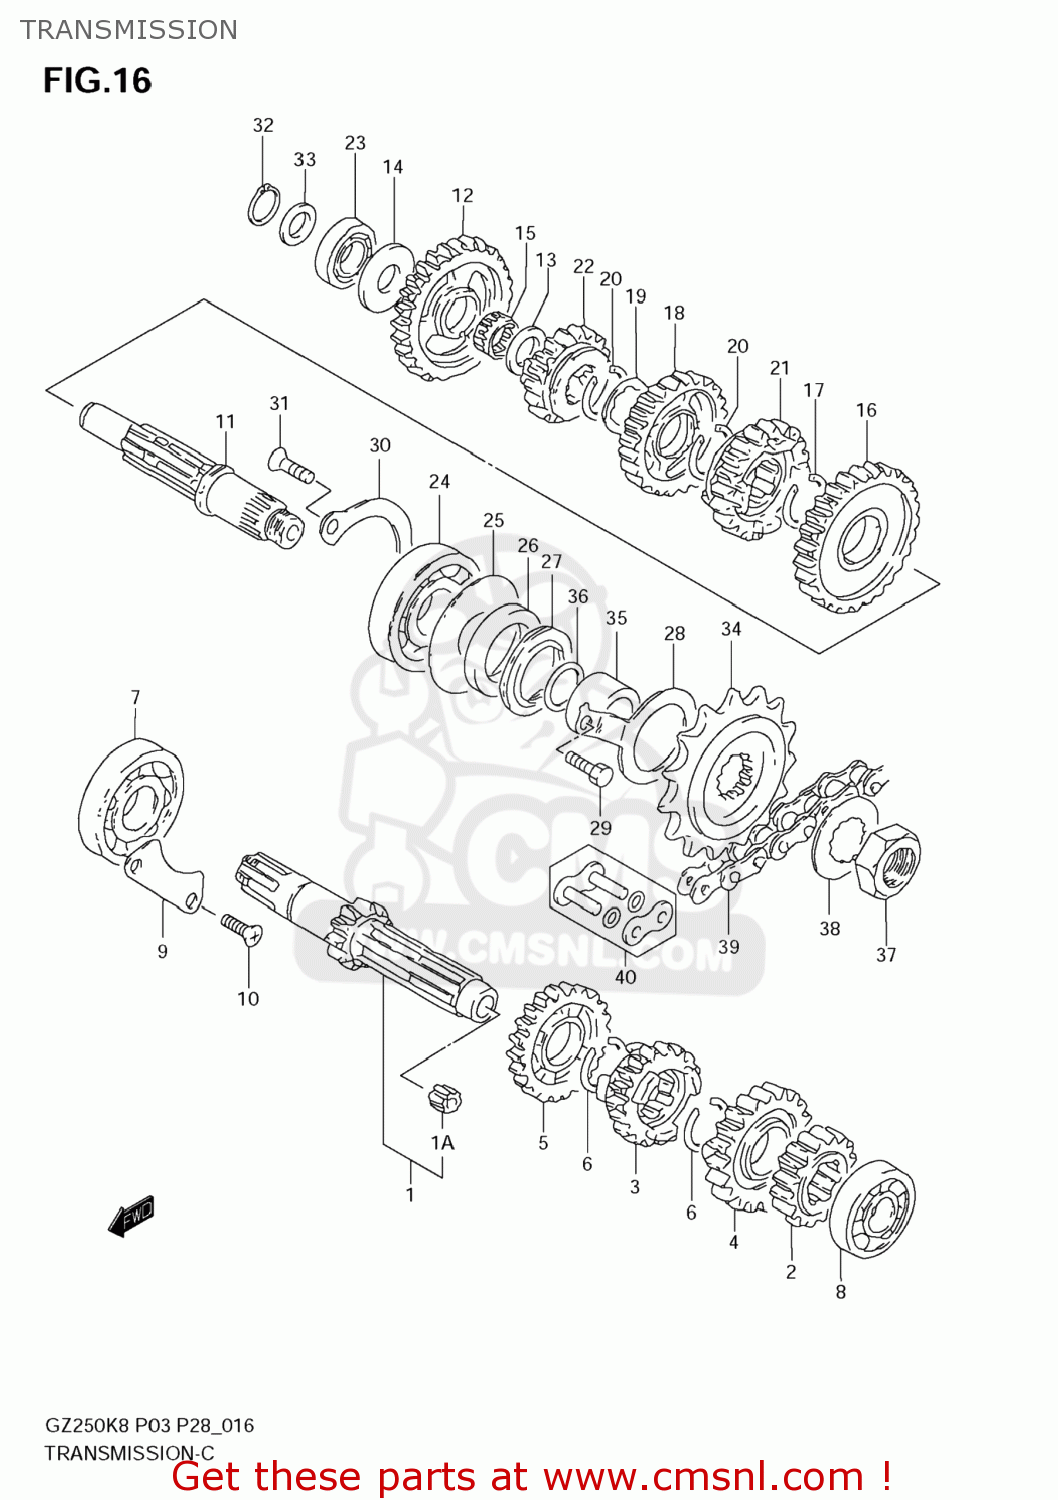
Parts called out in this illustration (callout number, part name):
1	SHAFT,COUNTER(NT:11)
1A	BUSH
2	GEAR,2ND DRIVE(NT:16)
3	GEAR,3RD DRIVE(NT:19)
4	GEAR,4TH DRIVE(NT:20)
5	GEAR,5TH DRIVE(NT:22)
6	CIRCLIP
7	BEARING(22X56X16)
8	BEARING(17X40X12)
9	RETAINER,CNTR SHAFT BEARING
10	BOLT(6X12)
11	SHAFT,DRIVE
12	GEAR,1ST DRIVEN(NT:29)
13	SHIM(17X28X1)
14	WASHER
15	BEARING(17X21X9.8)
16	GEAR,2ND DRIVEN(NT:27)
17	CIRCLIP
18	GEAR,3RD DRIVEN(NT:24)
19	WASHER,LOCK
20	CIRCLIP
21	GEAR,4TH DRIVEN(NT:20)
22	GEAR,5TH DRIVEN(NT:18)
23	BEARING(17X36X12)
24	BEARING(22X56X16)
25	WASHER(35X55X1)
26	SEAL,OIL(30X43X5)
27	SEAL,OIL(30X43X7)
28	RETAINER,DRIVE SHAFT OIL SEAL
29	BOLT
30	RETAINER,DRIVE SHAFT BEARING
31	SCREW
32	CIRCLIP
33	SHIM(17X24X1)
34	SPROCKET, ENGINE (NT:15)
35	SPACER
36	O RING(D:2.5,ID:21)
37	NUT
38	WASHER,LOCK
39	CHAIN ASSY (DID520VC5, 110LE)
40	JOINT SET OPT
